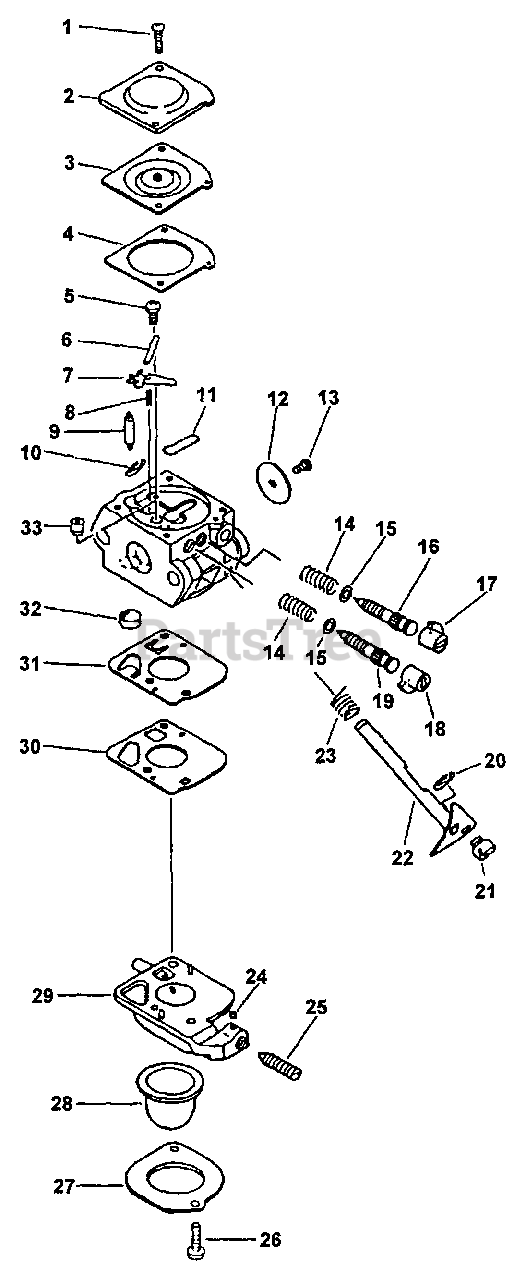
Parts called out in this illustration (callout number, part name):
2	COVER, METERING
3	DIAPHRAGM, METERING
4	GASKET, METERING
5	SCREW, METERING LEVER PIN
6	PIN, METERING LEVER
7	LEVER, METERING
8	SPRING, METERING LEVER
9	VALVE, INLET NEEDLE
10	RING, RETAINING
11	PLUG, WELCH
12	VALVE, THROTTLE
16	NEEDLE - LOW SPEED
17	CAP, LIMITER
18	CAP, LIMITER
19	NEEDLE - HIGH SPEED
20	RING, RETAINING
22	SHAFT, THROTTLE
23	SPRING, RETURN
24	PIECE, FRICTION
25	SCREW, IDLE ADJUST
26	SCREW, RETAINER
27	RETAINER, PURGE BULB
28	BULB, PURGE
29	BASE, PURGE
30	GASKET, PURGE
31	DIAPHRAGM, PURGE
32	STRAINER
33	NOZZLE, CHECK VALVE
